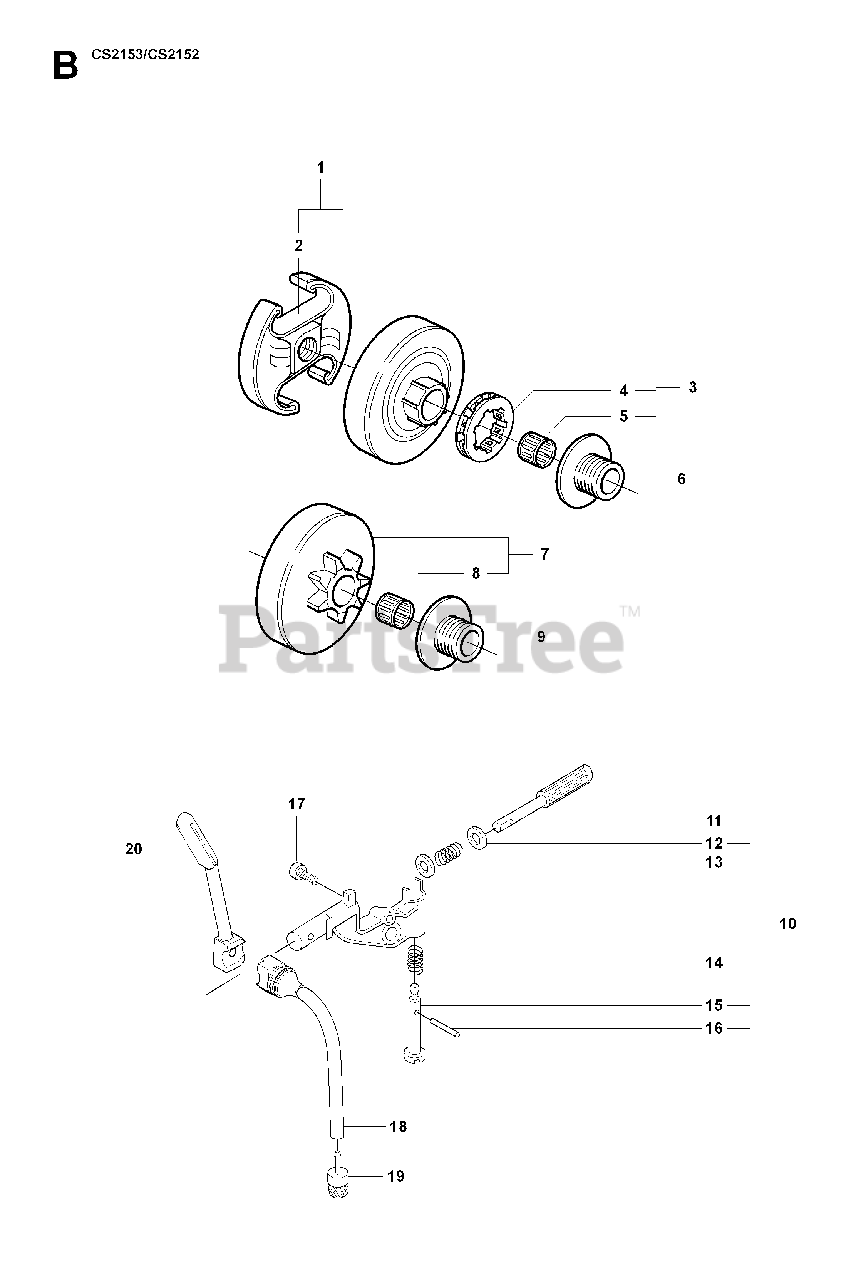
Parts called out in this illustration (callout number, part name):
2	SPRING
3	%CLUTCH DRUM
4	RIM SPROCKET 7T .325
5	NEEDLE BEARING
6	%PINION
7	CLUTCH DRUM
8	NEEDLE BEARING
10	OIL PUMP ASSY
11	PUMP PISTON
18	HOSE
19	OIL PLUMMET
20	OIL PRESSURE HOSE
